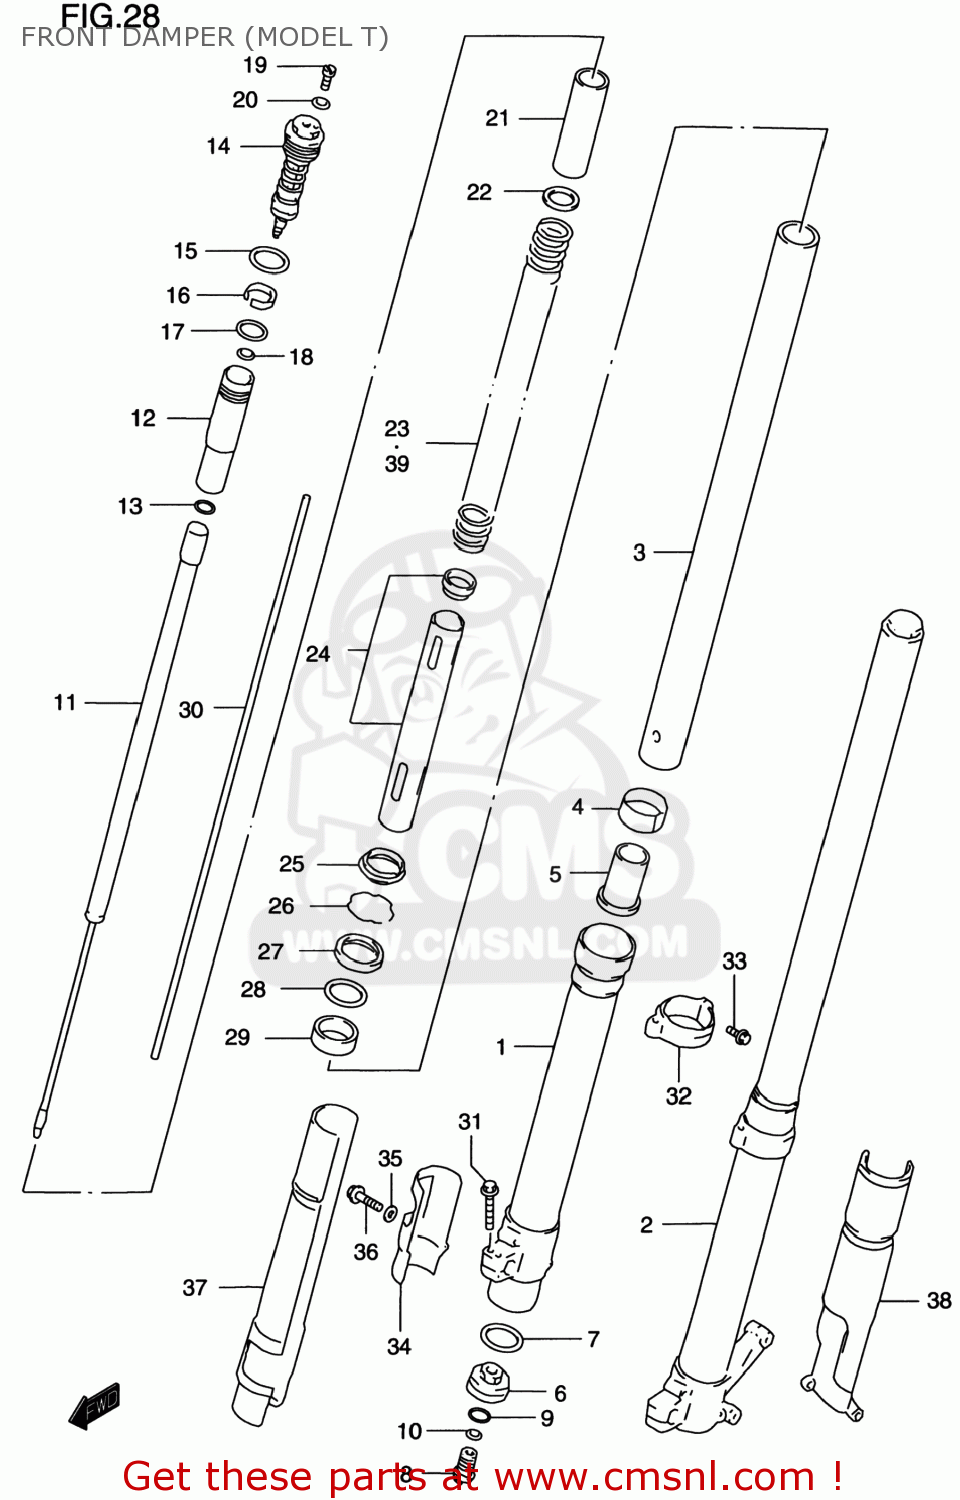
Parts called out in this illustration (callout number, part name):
1	TUBE,OUTER,R
2	TUBE,OUTER,LEFT
3	TUBE,INNER
4	BUSH,SLIDE
5	PIECE,OIL LOCK
6	PLATE,END
7	O RING
8	BOLT,CTR
9	GASKET (NAS)
10	O RING,CTR BOLT
11	DAMPER
12	TANK,SUB
13	O RING,CTR BOLT UPR
14	BOLT,FORK
15	O RING
16	BUSH,FORK BOLT SLIDE
17	O-RING,FORK BOLT,CENTER
18	O-RING,FORK BOLT,LOWER
19	BOLT,PLUG
20	O RING,PLUG
21	COLLAR,SPRING
22	JOINT,SPRING
23	SPRING,FR(K=0.40)
24	COLLAR,SPRING
25	SEAL,DUST
26	RING,STOPPER
27	SEAL,OIL
28	SPACER,SEAL
29	BUSH,GUIDE
30	ROD,PUSH
31	BOLT,HANDLE HOLDER(8X35)
32	GUIDE,FR PROTECTOR,R
33	BOLT,PROTECTOR GUIDE,6
34	PROTECTOR,OUTER TUBE,R
35	WASHER
36	BOLT
37	PROTECTOR,OUTER TUBE,R
38	PROTECTOR,OUTER TUBE,L
39	SPRING,FRONT (K=0.38)
